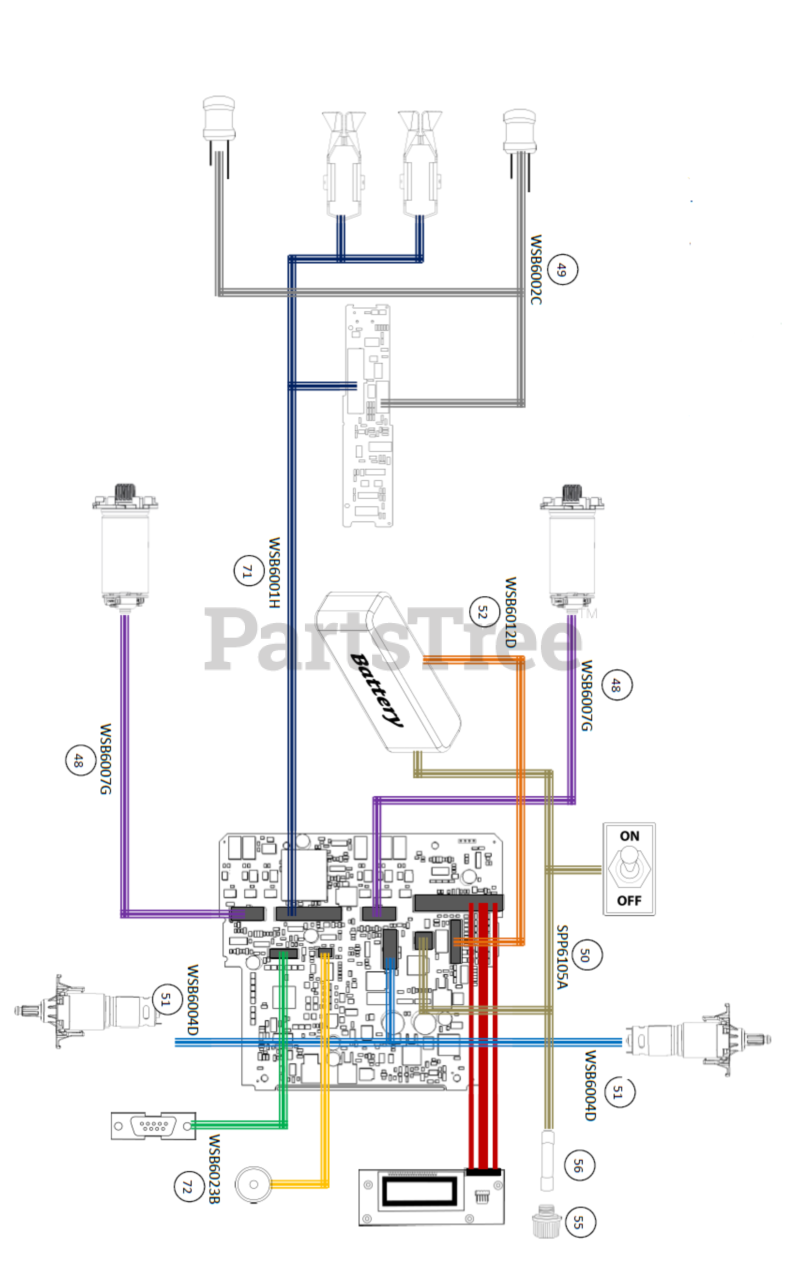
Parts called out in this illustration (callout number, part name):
48	MAIN BOARD TO MOW MOTOR CABLE BL
49	WIRE SENSORS CABLE W/HOLDERS
50	FUSE-BATTERY CABLE
51	MAIN BOARD TO DRIVE MOTOR CABLE
52	MAIN BOARD TO BATTERY CELLS CABLE
55	FUSE THREAD
56	FUSE-32V/20A FAST
71	MAIN BOARD TO FRT WHEEL CABLE (18)
72	RS COMMUNICATION/GSM SPLIT CABLE
